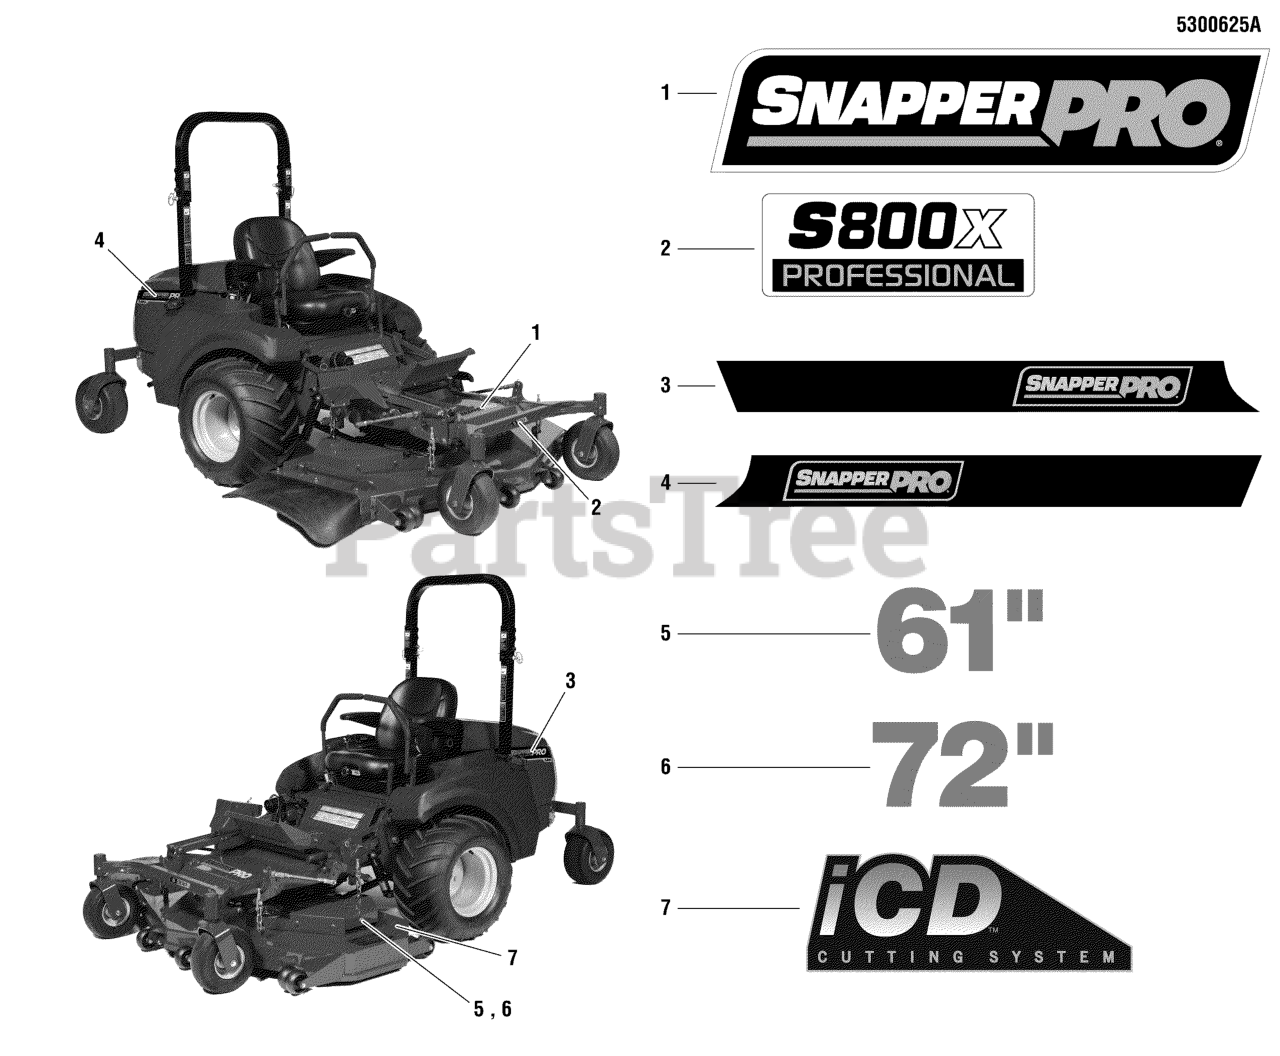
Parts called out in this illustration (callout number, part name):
1	DECAL, SNAPPER PRO LOGO, LARGE
2	DECAL, S800X (2014)
3	DECAL, S800X STRIPE, LH (2014)
4	DECAL, RH STRIPE, S800X (2014)
5	DECAL, 61
6	DECAL, 72
7	DECAL, iCD CUTTING SYSTEM
